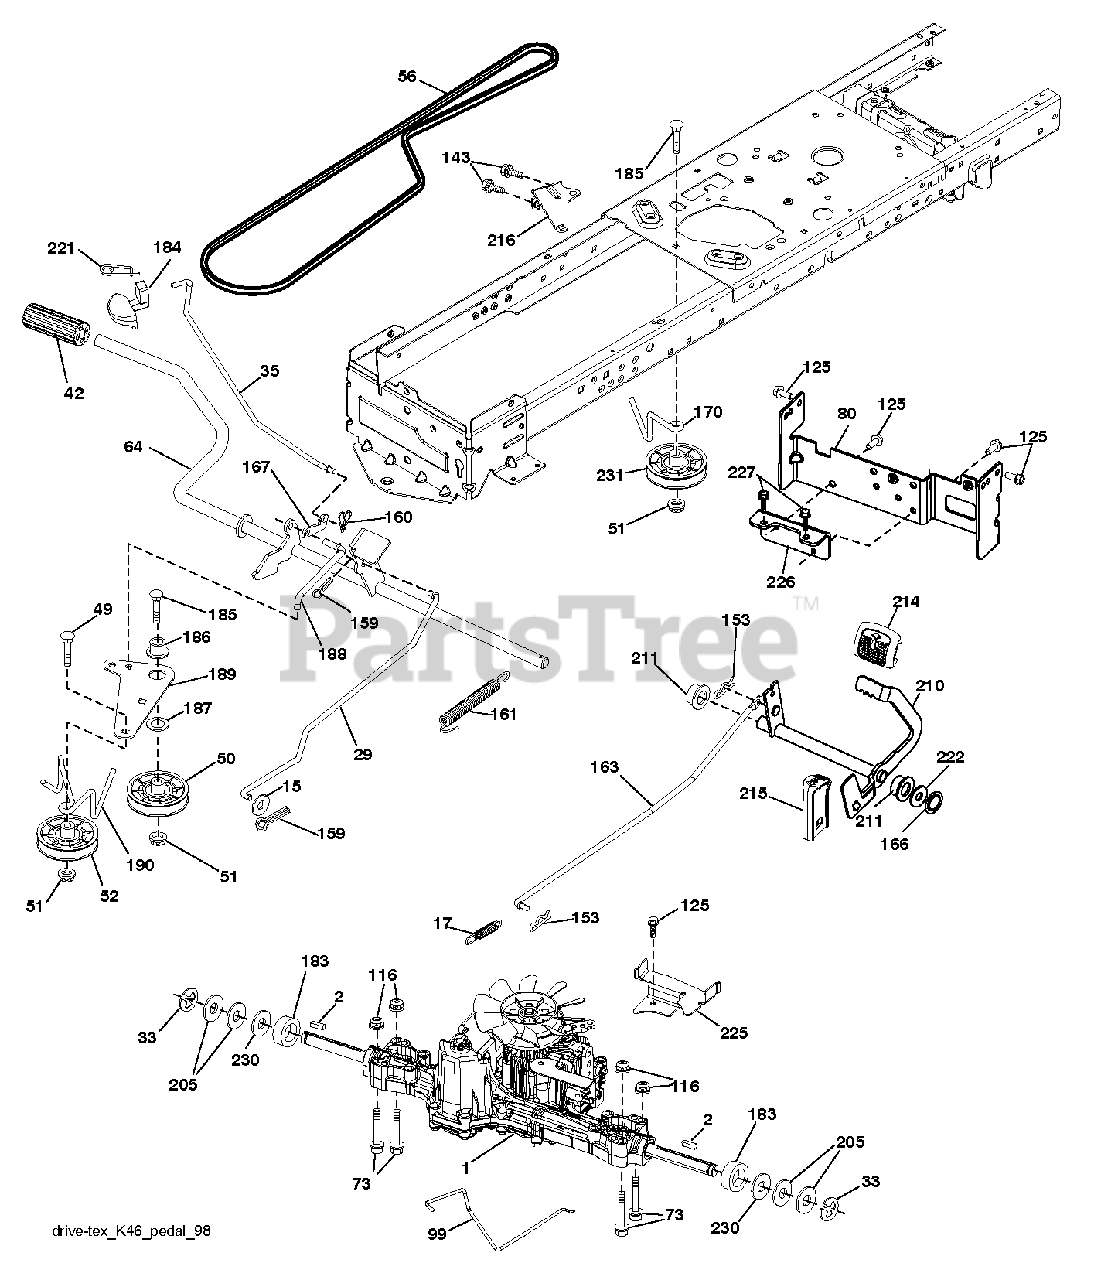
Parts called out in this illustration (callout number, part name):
2	SQUARE KEY
15	WASHER
17	SPRING, BREAK
29	ROD.BRAKE.K46
33	E-RING LT
42	PEDAL COVER T
50	IDLER.FLAT.910.OFFSET
52	IDLER.V-GROOVE.910.OFFSET
64	SHAFT.ASM.PEDAL.BRK.CN
99	ROD.SPRING.BYPASS.K46.LT.Z
116	NUT LOCK HEX FLANGE 5/16-18
125	SCREW
143	SCREW LT
159	COTTER PIN
160	RETAINER CLIP
161	SPRING, RETURN LT
166	NUT.PUSH.625
167	LATCH BRAKE PARKING
170	KEEPER.CENTER SPAN.1.688
183	SPACER AXLE
186	SPACER.RETAINER
188	LINK.CLUTCH.GROUND DRI
189	BELLCRANK.GRDDRIVE.NST
190	KEEPER.BELLCRANK.DRIVE
210	ROCKER.ASM.PEDAL.CONTR
211	BEARING RER
214	PAD PEDAL FORWARD
215	PEDAL.REVERSE.TEX.GT.4
216	BRKT.PULLEY.IDLER.WTEX
221	RETAINER.SPRING.CLIP.H
222	WASHER 21/32 X 1-1/4 X 10 GA.
225	KEEPER.BELT.TRANSAXLE.
226	BRACKET MOUNT TORQUE
231	PULLEY VGROOVE
